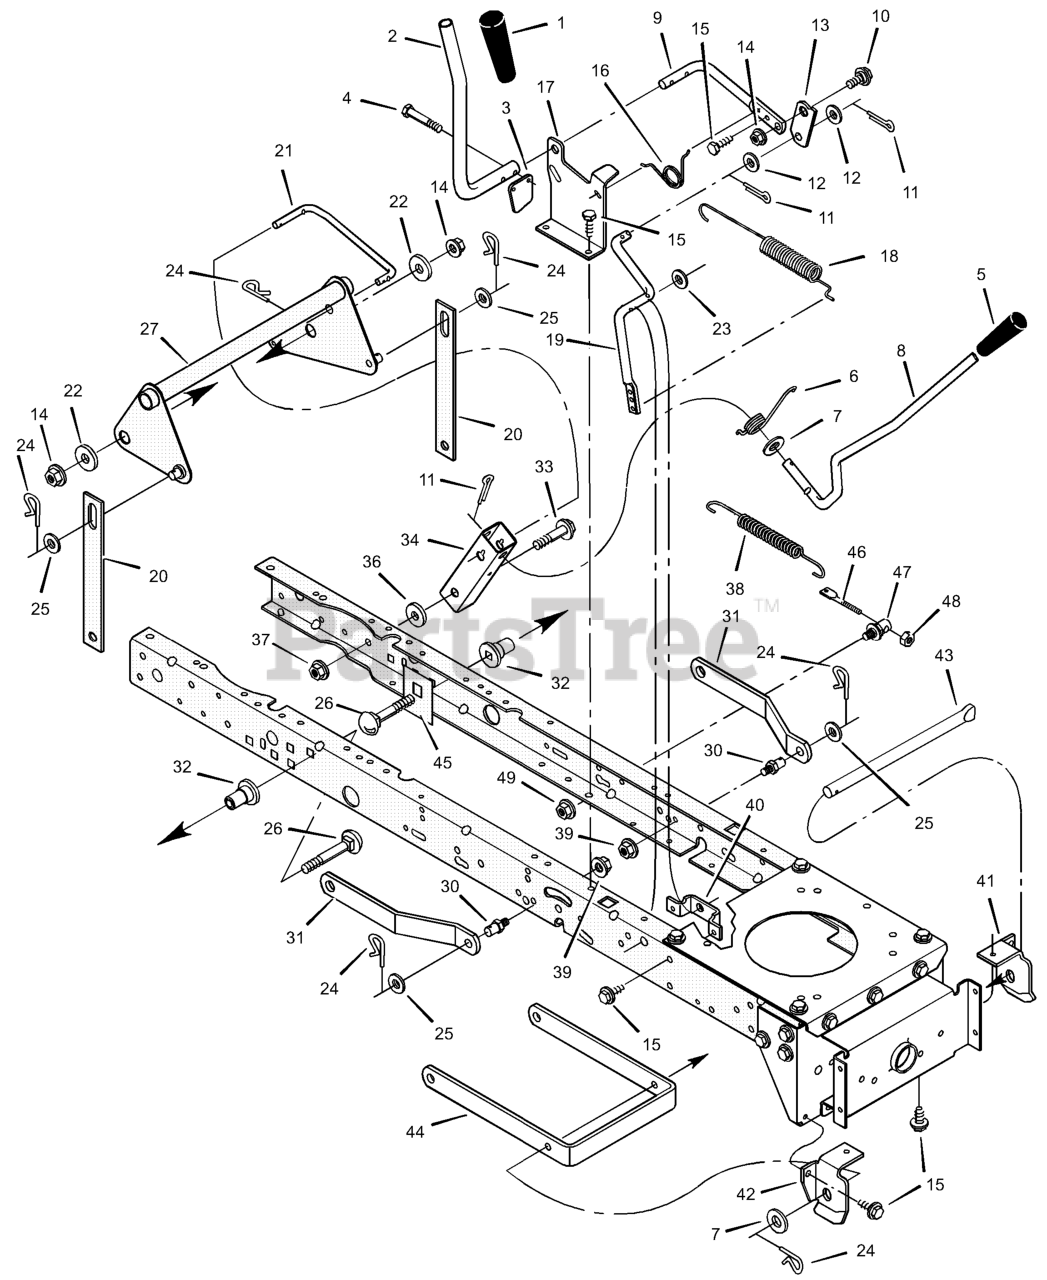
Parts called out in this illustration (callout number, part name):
1	Grip
2	Handle, PTO
3	Pad, Switch
4	Screw, Hex
5	Grip
8	Lever, Lift
9	Lever, PTO
10	Bolt, Shoulder
11	Pin, Cotter
12	Washer
13	Link, PTO
14	Nut, Flange
17	Bracket, PTO
19	Crank, PTO
20	Link, Lift
21	Link, Lift Handle
24	Pin, Hair
26	Bolt, Carriage
27	Lever Assembly, Lift
30	Pin
31	Bracket, Rear Suspension
32	Spacer, Lifter
33	Bolt, Shoulder
34	Bracket, Pivot
37	Nut, Flange
39	Nut, Flange
40	Bracket, PTO
41	Hanger, Left Deck
42	Hanger, Right Deck
43	Rod, Hanger
44	Bracket, Suspension
45	Plate, Stiffening
47	Stud, Swivel
48	Nut
49	Nut
